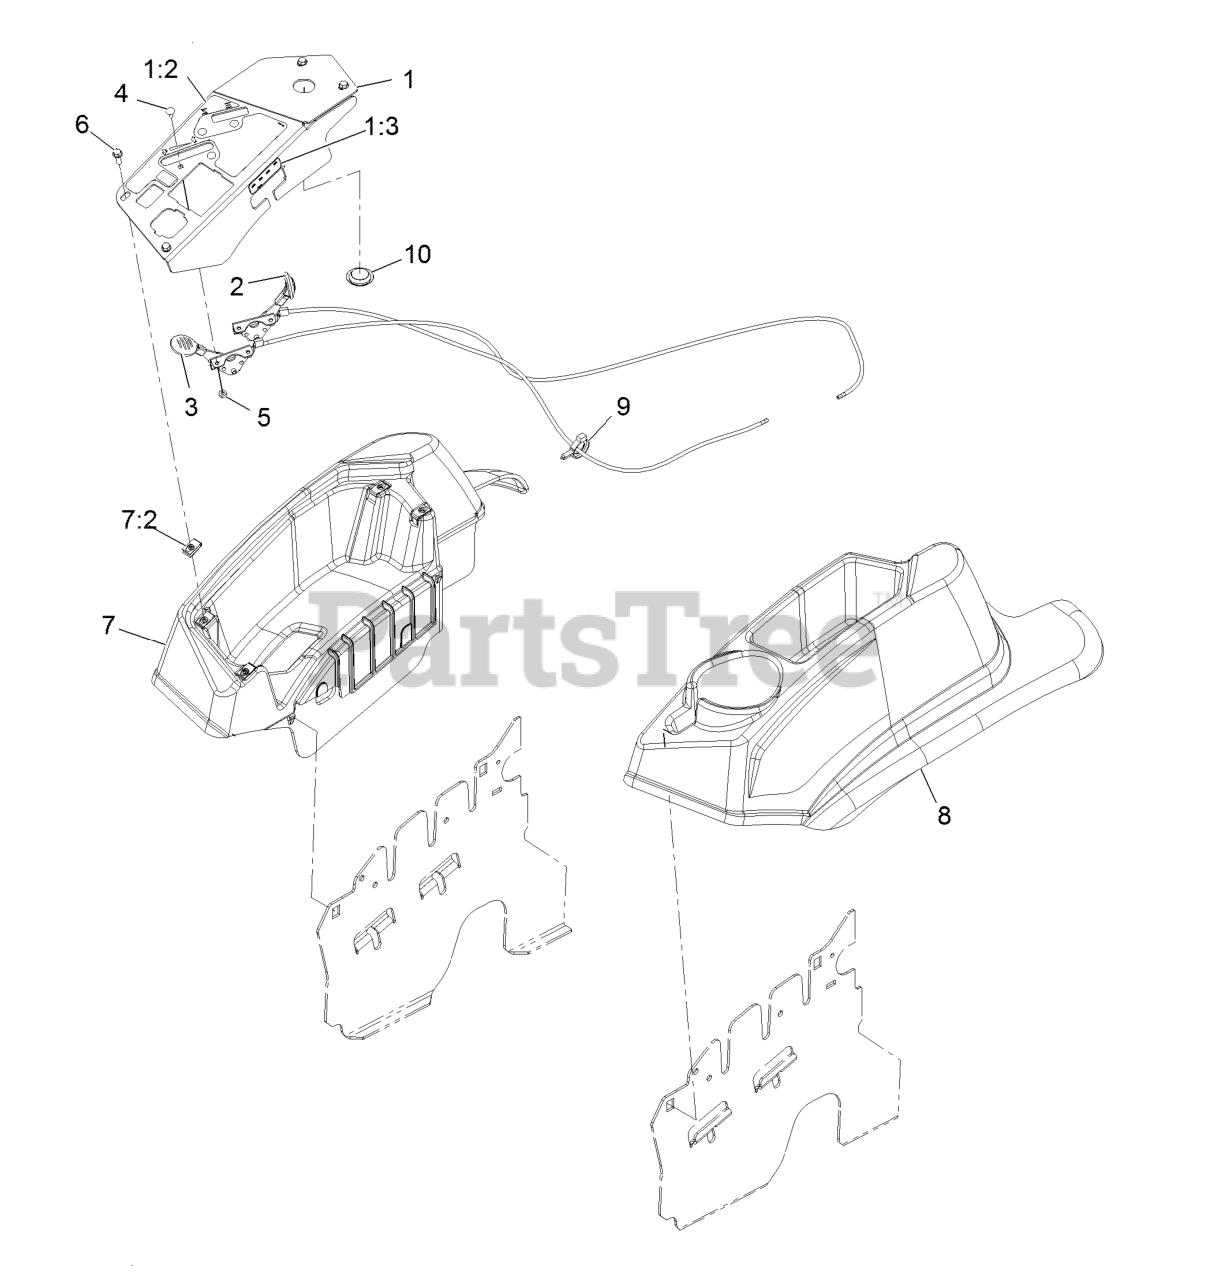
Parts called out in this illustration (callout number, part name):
1	CONSOLE,PANEL W/DECAL
1:2	DECAL-CONTROL PANEL
1:3	DECAL-FUSE
2	ASM, CHOKE CABLE
3	ASM,THROTTLE CABLE
4	BOLT-CARR
5	NUT-LOCK, NI
6	SCREW-HWH
7	CONSOLE,RH AS ASM
7:2	Nut-Retainer-Panel 1/4-20
8	CONSOLE, LH AS
9	CLAMP-HOSE
10	PLUG-PLASTIC
